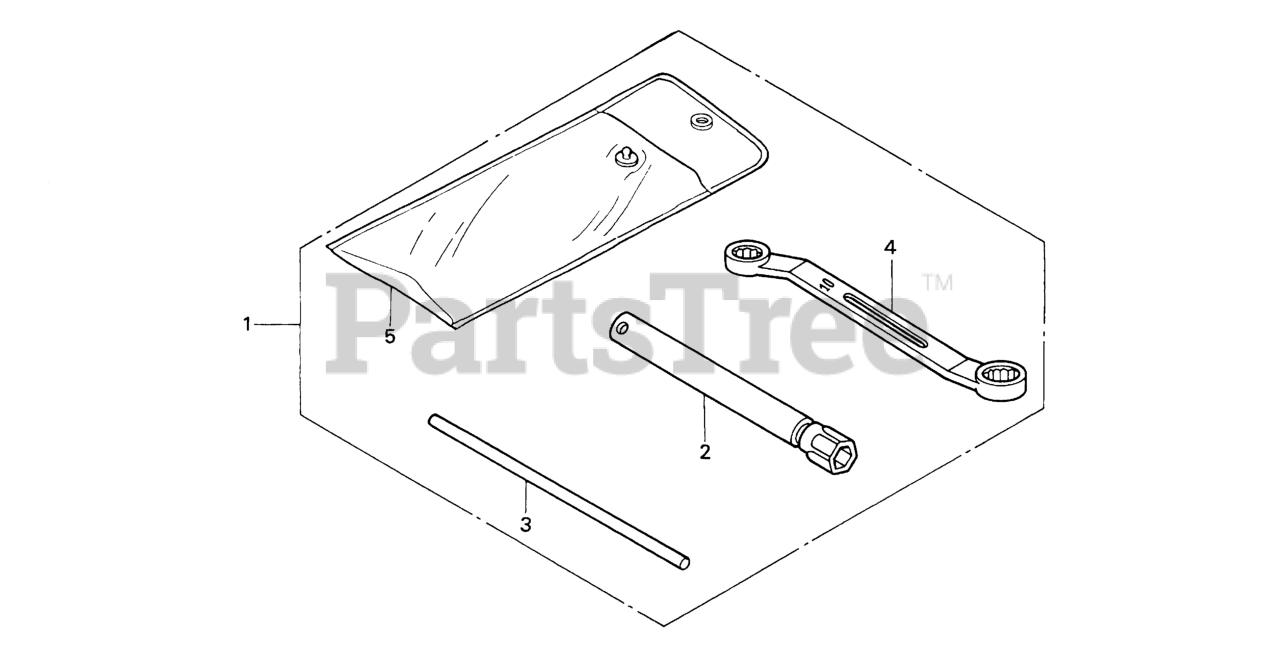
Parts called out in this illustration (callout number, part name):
1	TOOL KIT
2	WRENCH, SPARK PLUG
3	HANDLE, BOX WRENCH (NOT AVAILABLE)
4	WRENCH, EYE (10X12)
5	BAG, TOOL (230MM)
